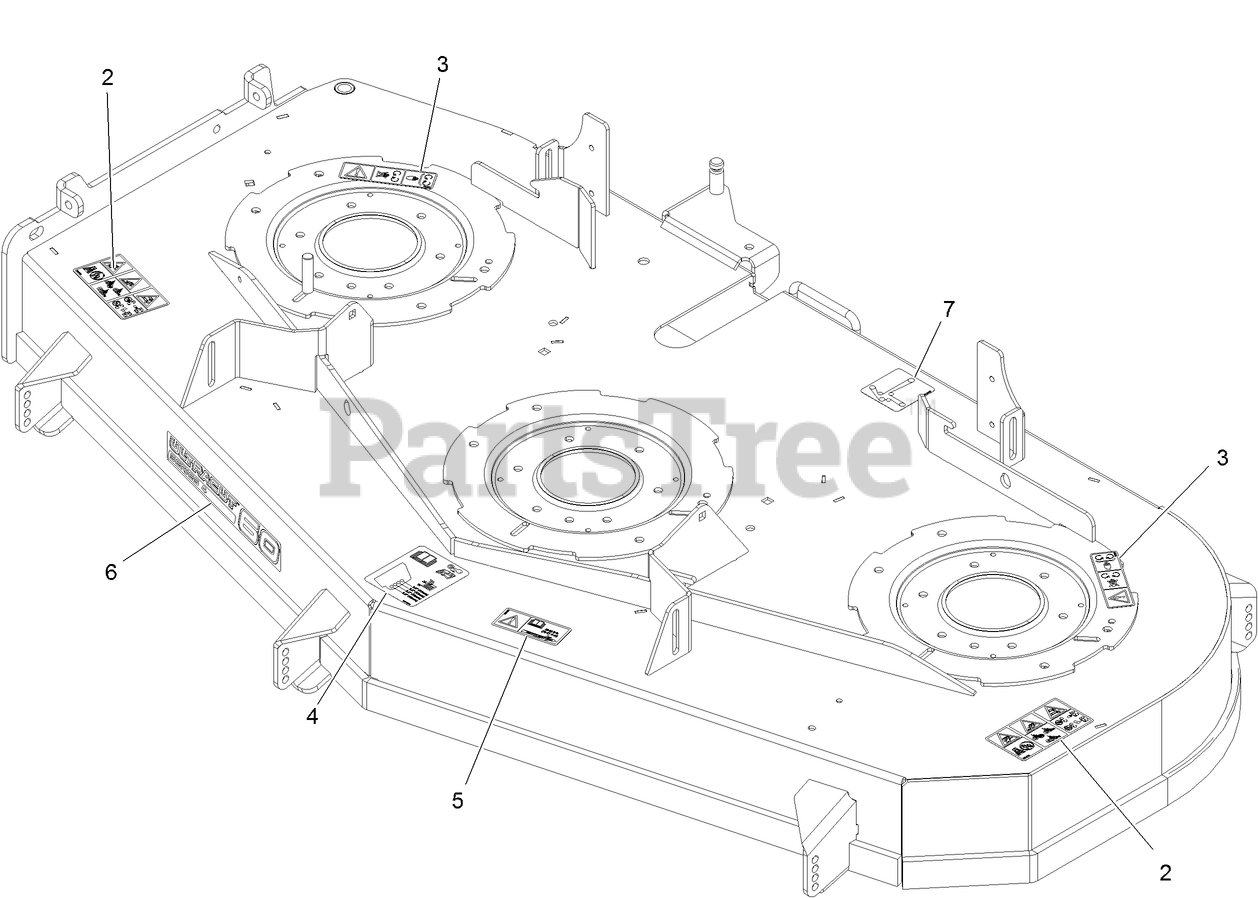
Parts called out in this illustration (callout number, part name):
2	DECAL-DANGER THROWN OBJECTS
3	DECAL-COVER, MISSING
4	DECAL-ROLLER, ANTI-SCALP
5	DECAL-TORQUE, BOLT
6	DECAL, 604
7	DECAL-ROUTING, BELT
